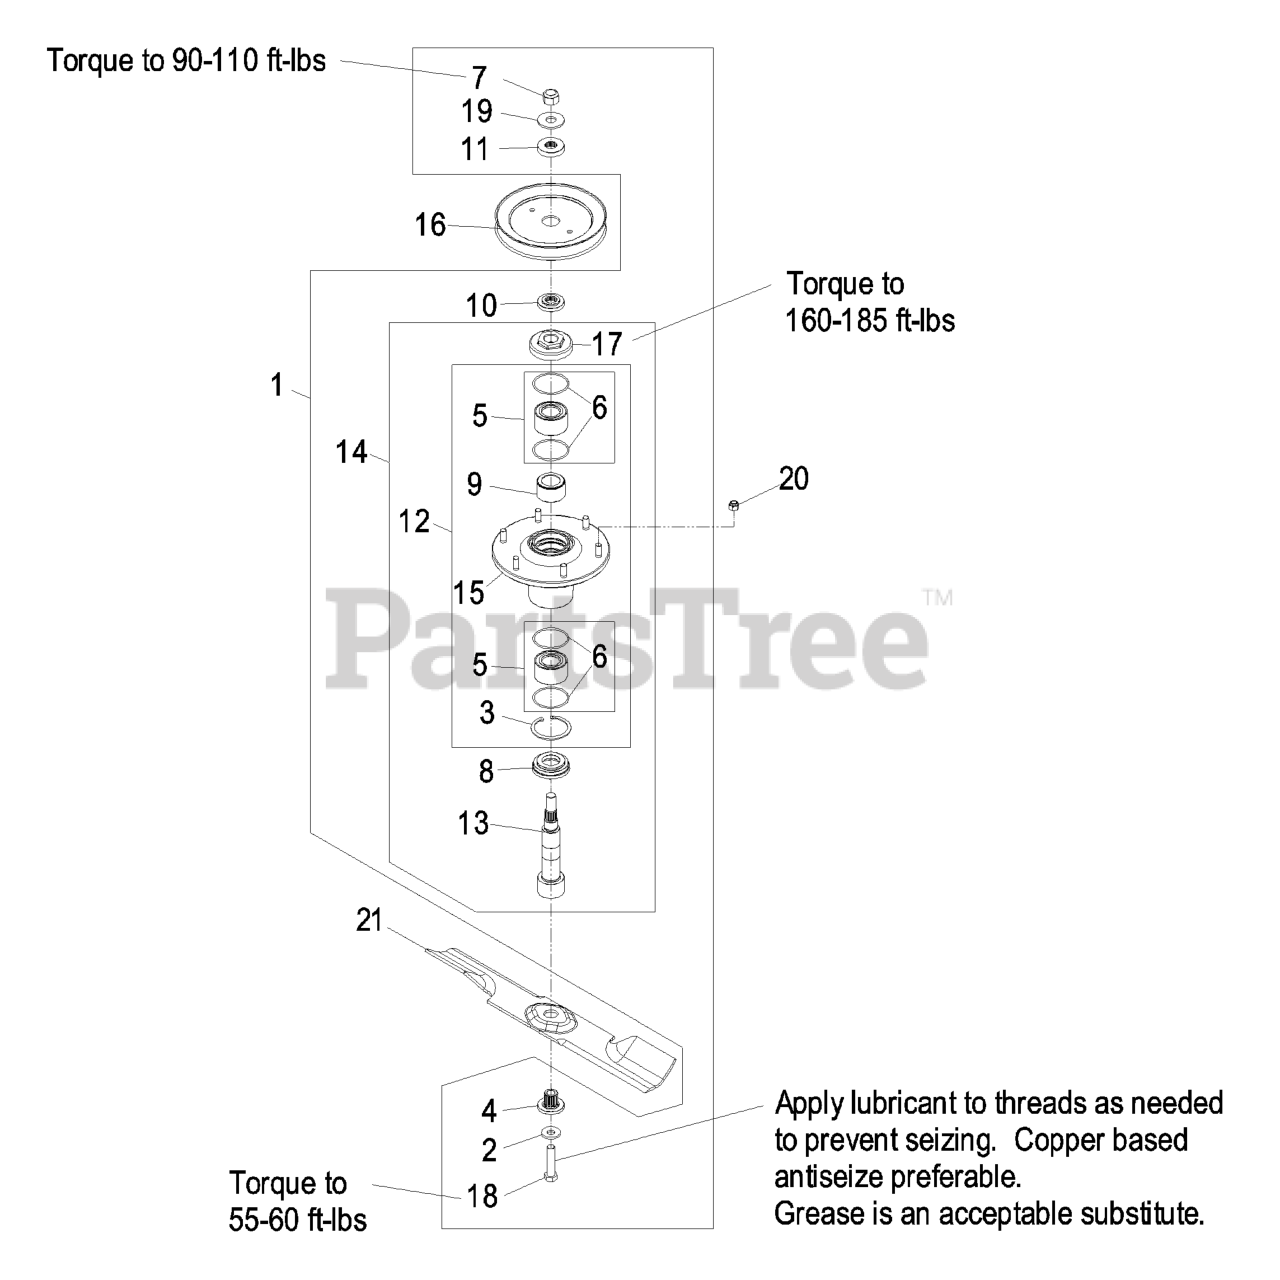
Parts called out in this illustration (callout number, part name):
1	ASM, CUTTER HSG W/MNT HRD
2	WASHER-SPRING
3	RING-RETAINING
4	BUSHING,SPLINED
5	ASM, BEARING W/ORINGS
7	NUT-LOCK NI
8	GUARD,BOTTOM
9	SPACER,BEARING
10	SPACER,SPLINED STEPPED
11	SPACER,SPLINED
12	ASM,CUTTER HOUSING
15	ASM,HOUSING W/STUDS
16	SHEAVE, BLADE DRIVE 6.13
18	SCREW-HH
19	WASHER-FLAT
20	NUT-LOCK, NI
